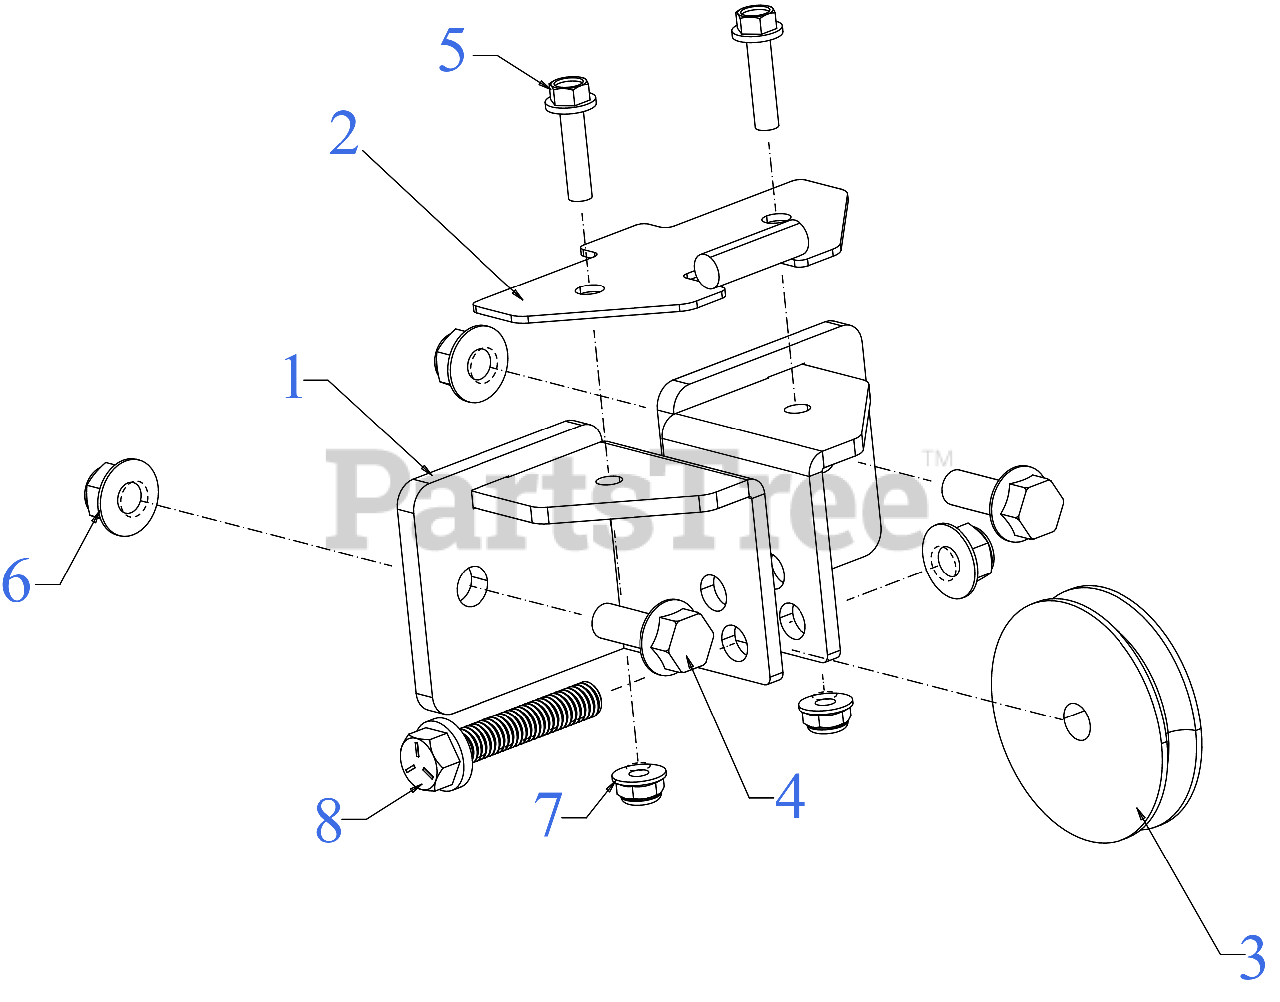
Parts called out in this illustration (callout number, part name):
1	MAIN BRACKET
2	COVER PLATE
3	ALUMINUM 2" ROLLER
4	HEX SCREW 3/8-16
5	SCREW 1/4-20 x 1.0
7	FLANGE LOCK NUT
8	SCREW 3/8-16 x 2.00 GR5
